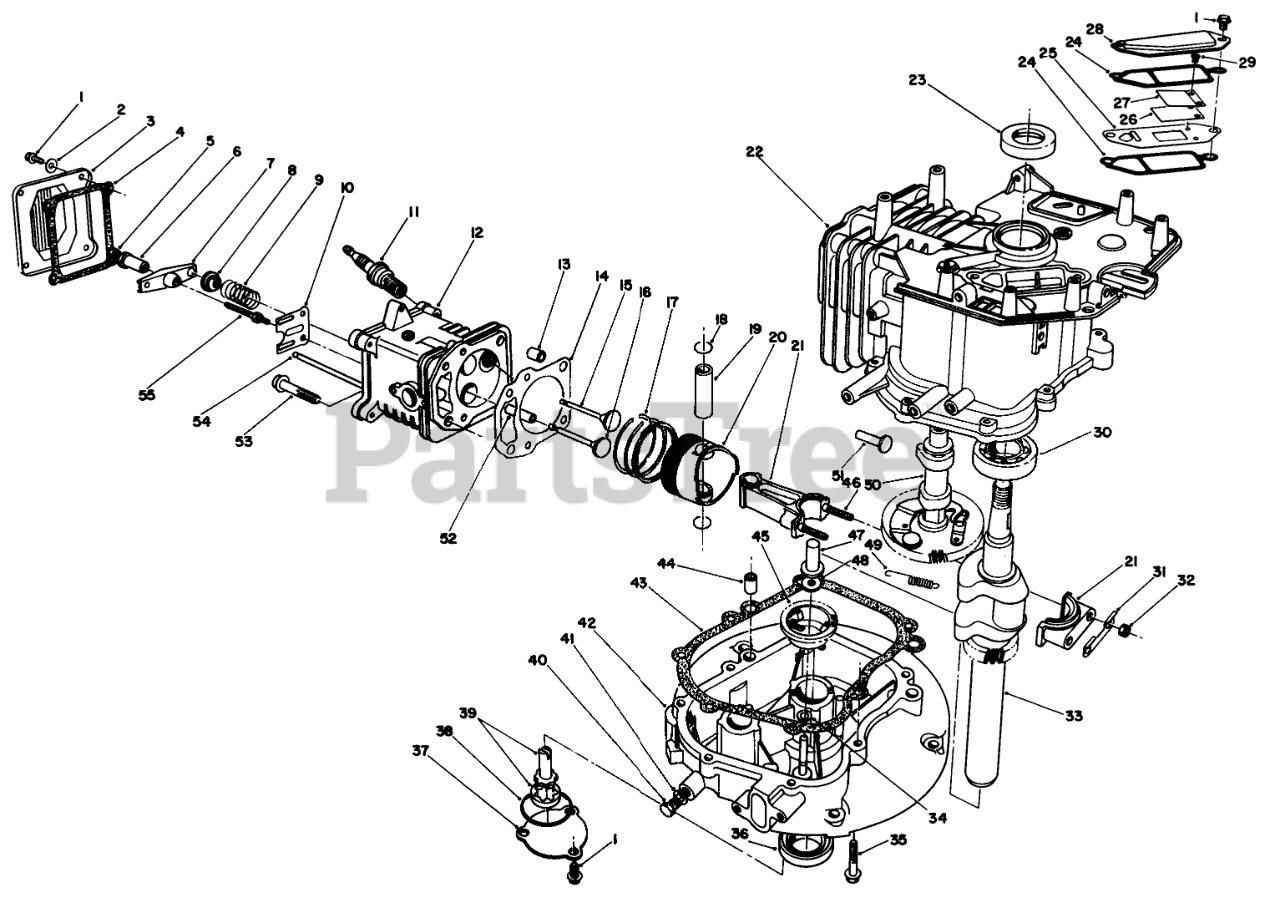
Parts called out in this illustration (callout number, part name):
2	WASHER
3	COVER
4	GASKET
6	PIVOT
8	RETAINER
9	SPRING
10	GUIDE
11	SPARK PLUG
12	Head-Cylinder (Incl. Ref. #52)
14	GASKET
15	VALVE-INTAKE
16	VALVE-EXHAUST
17	RING SET
18	CIRCLIP
20	PISTON
21	Connection Rod Assembly (Incl. Ref. #31, 32, & 46)
22	Block-Engine (Incl. Ref. #23, & 30)
24	GASKET
25	Plate-Breather
26	Valve-Reed
27	Retainer-Reed Valve
28	COVER
29	Screw-Reed Valve
30	BEARING
31	Plate-Lock
33	CRANKSHAFT
34	WASHER
37	COVER
38	O-RING
39	OIL PUMP
40	OIL DRAIN PLUG
41	GASKET
42	Crankcase
43	GASKET
45	GOVERNOR FLYWEIGHT ASM
47	PLUNGER
48	WASHER
49	SPRING
50	Camshaft Assembly (Incl. Ref. #49)
51	TAPPET
52	GUIDE
